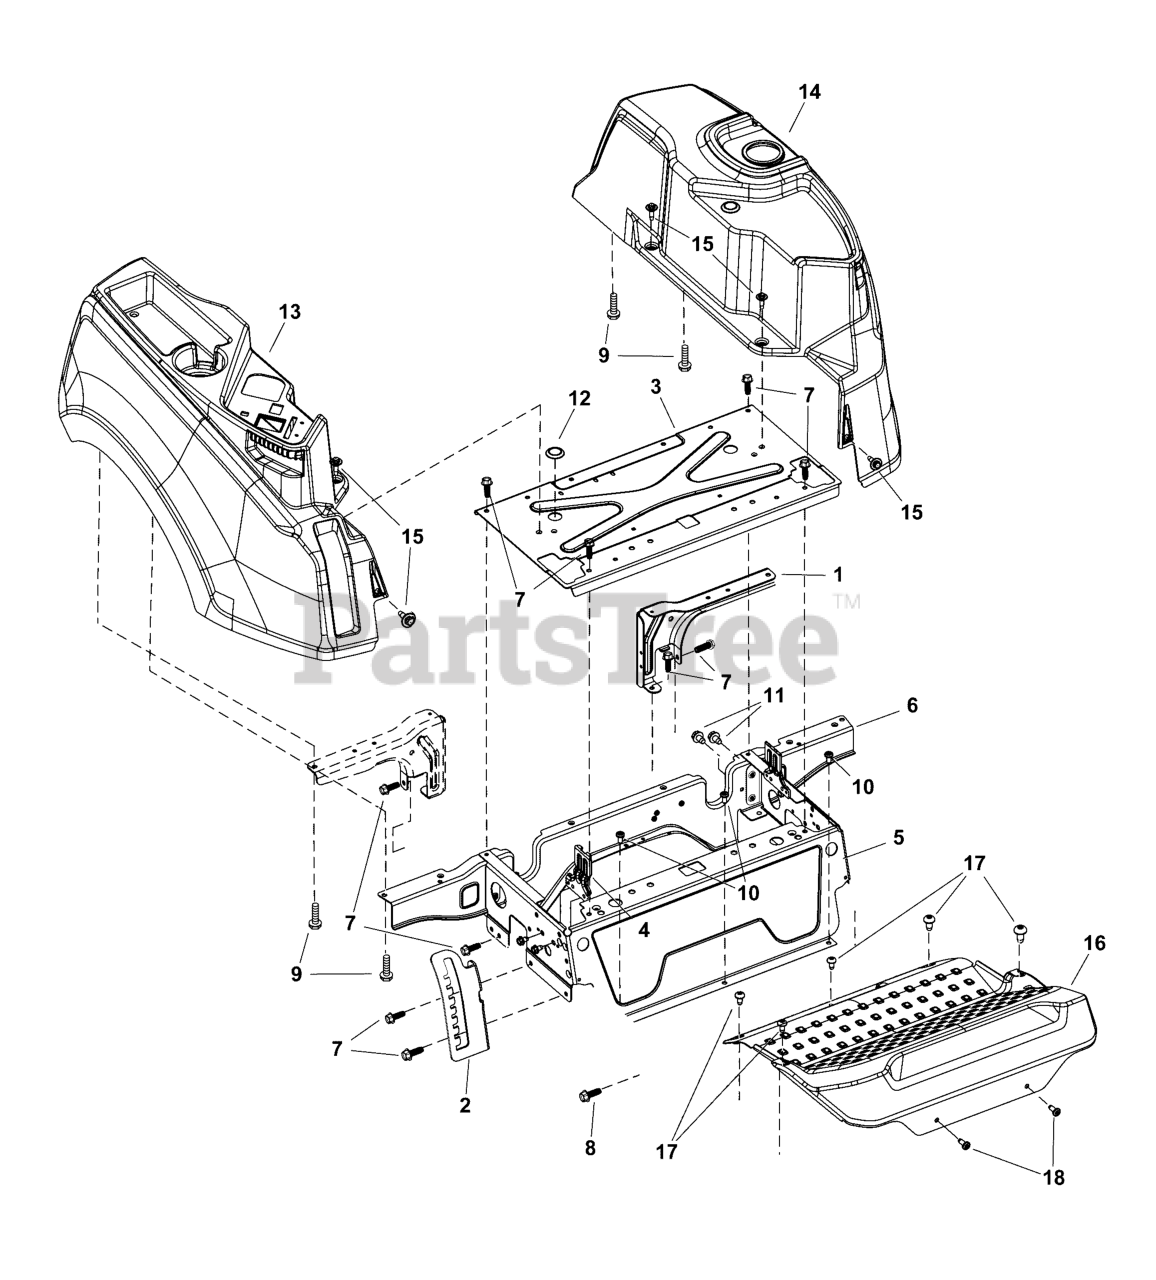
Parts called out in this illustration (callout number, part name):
1	BRACKET, Rear Tank
2	BRACKET, Height Index
3	PLATE, Seatbox Top
4	BRACKET, Lapbar Brace
5	FRAME, Seat
6	BRACE, Rear Seatbox Brace
7	SCREW, 5/16-18 X .750, Hex Washer
8	CAPSCREW, Hex Head, 3/8-16 x 1, GR5
9	SCREW, 5/16-14 X 1.0
10	SCREW, 5/16-18 X .750
11	SCREW, 5/16-18 X .500
13	CONSOLE, (RH)
14	CONSOLE, (LH)
15	SCREW, M6-1 .368 X.115, Shoulder
16	FLOORBOARD
17	SCREW, 1/4-20 X .50
18	SCREW, 5/16-18, 0.750, Self-Tapping
